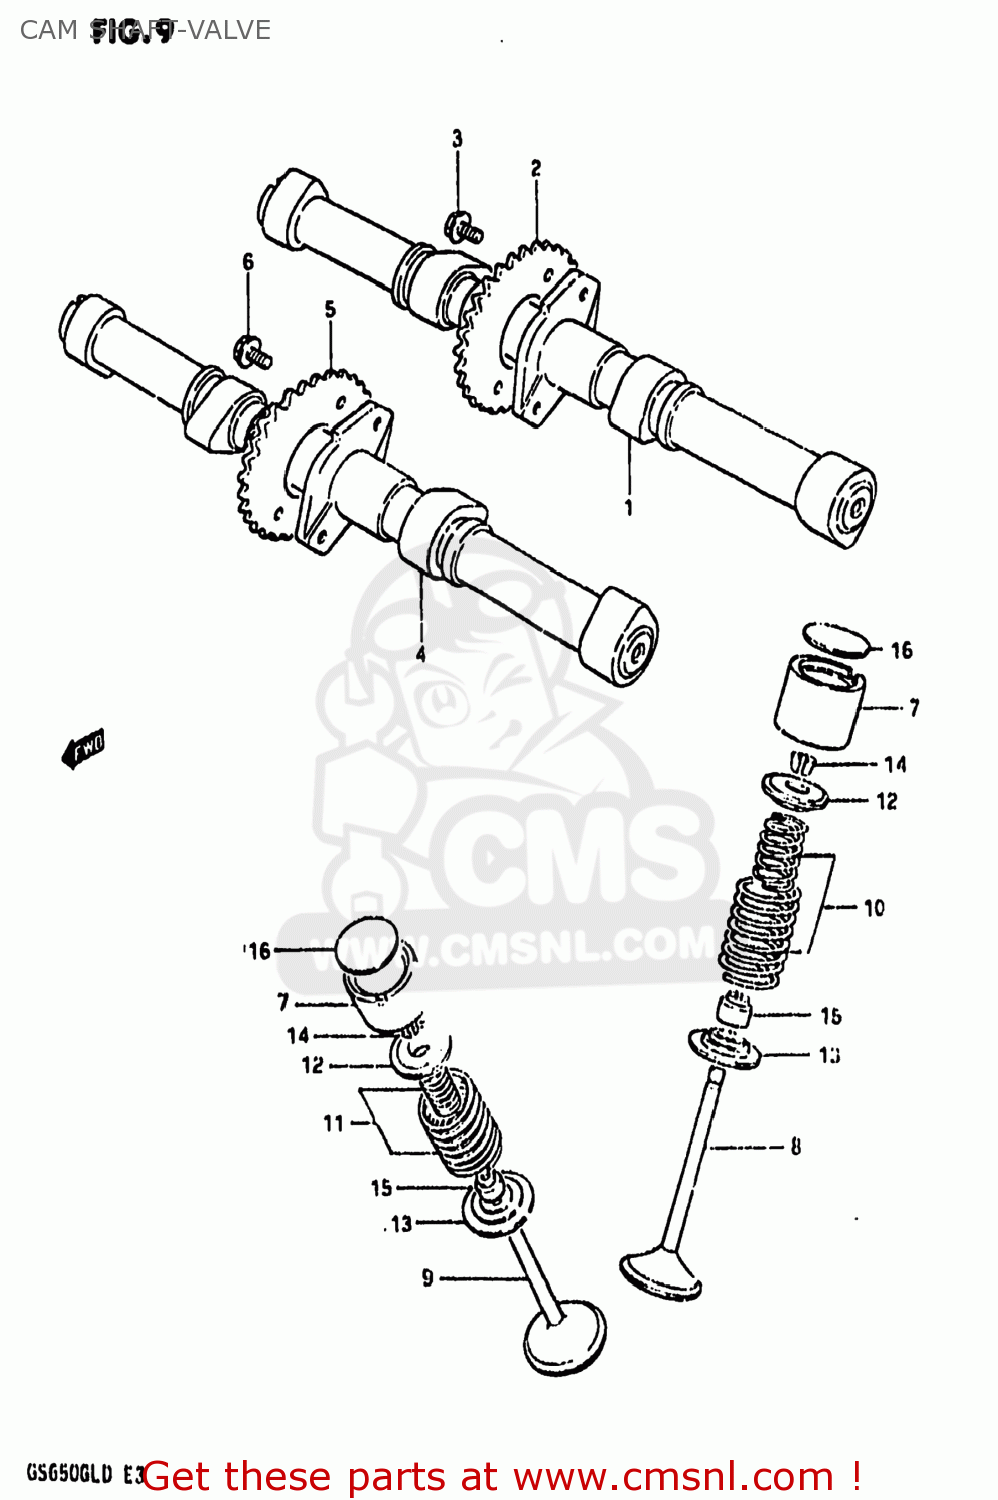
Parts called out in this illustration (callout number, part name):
1	CAMSHAFT,INTAKE
2	SPROCKET,INTAKE CAMSHAFT
3	BOLT(7X11)
4	CAMSHAFT,EXHAUST
5	SPROCKET,EXHAUST CAMSHAFT
6	BOLT(7X11)
7	TAPPET
8	VALVE,INTAKE
9	VALVE,EXHAUST
10	SPRING SET,VALVE
11	SPRING SET,EXHAUST VALVE
12	RETAINER,VALVE SPRING
13	SEAT,VALVE SPRING
14	COTTER VALVE
15	SEAL,OIL(7X14.4X9)
16	SHIM,TAPPET
17	SHIM SET,TAPPET
18	CASE
